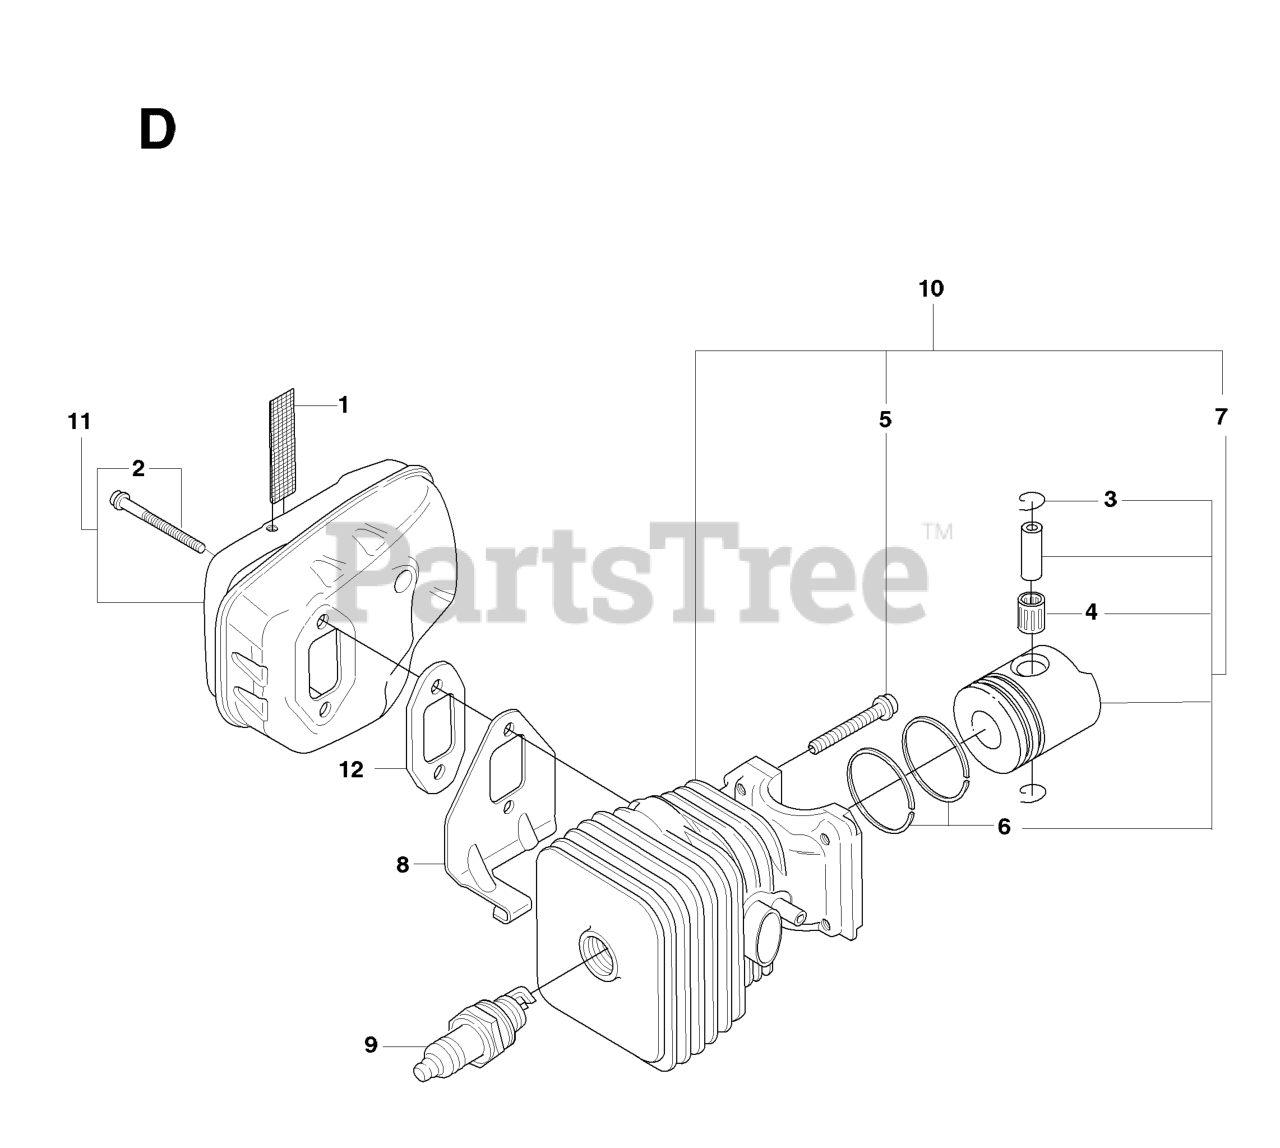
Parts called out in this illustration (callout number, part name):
1	SPARK ARRESTOR SCREEN
5	SCREW MC6S 5X35
6	PISTON RING
8	COOLING AIR CONDUCTOR
9	SPARK PLUG RCJ6Y NLA
10	CYLINDER COMPL
